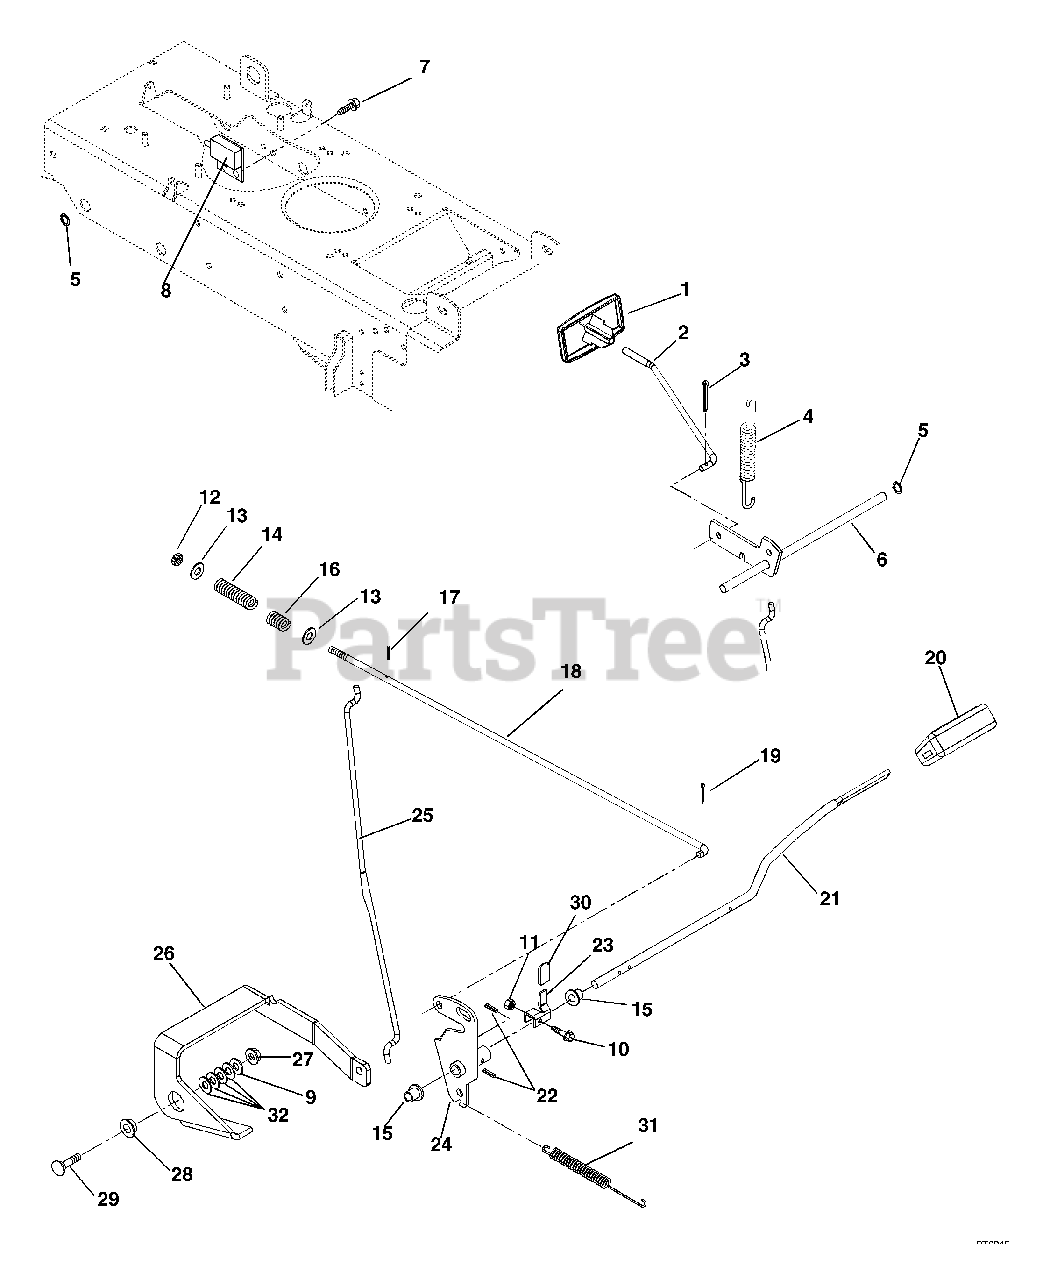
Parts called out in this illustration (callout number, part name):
1	KNOB, PARK BRAKE
2	ROD, PARKING BRAKE
3	PIN-COTR .06X.50
4	SG-TENS .051X.60X2.25 WLD 7.0
5	RG-RTNG-EXT .250X.010
6	BELLCRANK, PARKING BRAKE
7	SCR-TAP 12-24X.50 HWH TR BLACK
8	SWITCH,INTERLOCK
9	@WSHR-FL-STL.38X.875X.083 YWZC
10	@SCR-MCH 10-24X1.00 HWH YWZC
11	@NUT-LK-NYL 10-24 W/INSRT YWZC
12	@NUT-LK-CTR .38-16 YWZC
13	@WSHR-FL-STL.406X.812X.065 YWZ
14	SG-COMP 2.00X.404
15	BSHG-FLG .515X.750X.745X1.00NY
16	SG-COMP .62X.68X1.75
17	PIN-ROLL .125X.75
18	ROD-BRAKE
19	@PIN-CTR .09X.75 EXTPRSQCT YWZ
20	COVER - PEDAL - BRAKE
21	PEDAL - BRAKE
22	PIN-GRV .188X1.25 TP A
23	LEVER - BRAKE SWITCH
24	ARM + HUB - BRAKE
25	ROD, PARKING BRAKE
26	LEVER, PARKING BRAKE
27	@NUT-SPNLK-FLG .312-18 YWZC
28	BSHG, FLG .325X.499X.26X.88
29	BLT-RDHDSQNK .31-18X1.0 SHTYZ
30	GRIP .062 X .375 X 1.000 RE
31	SG-TENS .105X.85X5.00 WLD 40
32	WSHR-PLASTIC .390X.875X.062
